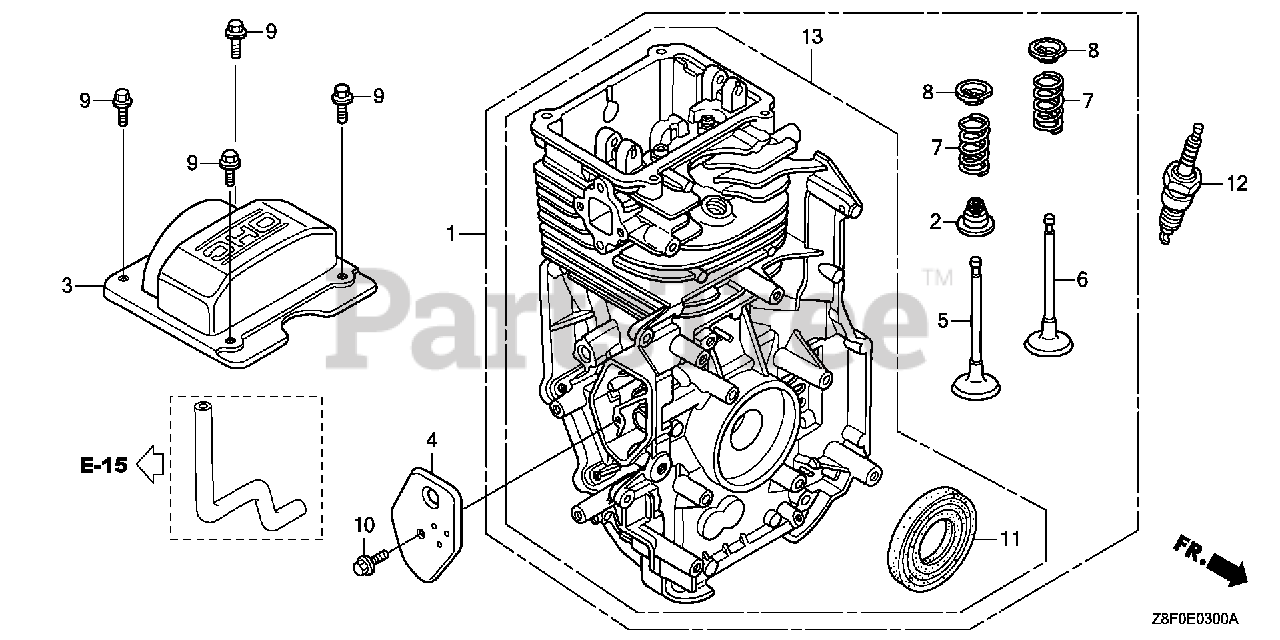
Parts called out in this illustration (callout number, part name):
1	CYLINDER ASSY.
2	SEAL, VALVE STEM
3	COVER, CYLINDER HEAD
4	COVER, BREATHER (Honda Code 5580006). (BREATHER VALVE ASSY.)
5	VALVE, IN. (TECHNOSTAR)
6	VALVE, EX. (L8E)
6	VALVE, EX. (C8E)
7	SPRING, VALVE
8	RETAINER, IN. VALVE SPRING
8	RETAINER, VALVE SPRING (EXHAUST SIDE)
9	BOLT, FLANGE (6X13)
9	BOLT, FLANGE (6X12) (CT200)
10	BOLT, FLANGE (6X14)
11	OIL SEAL (25.4X62X6)
12	SPARK PLUG (BPR6ES) (NGK)
13	CYLINDER ASSY.
